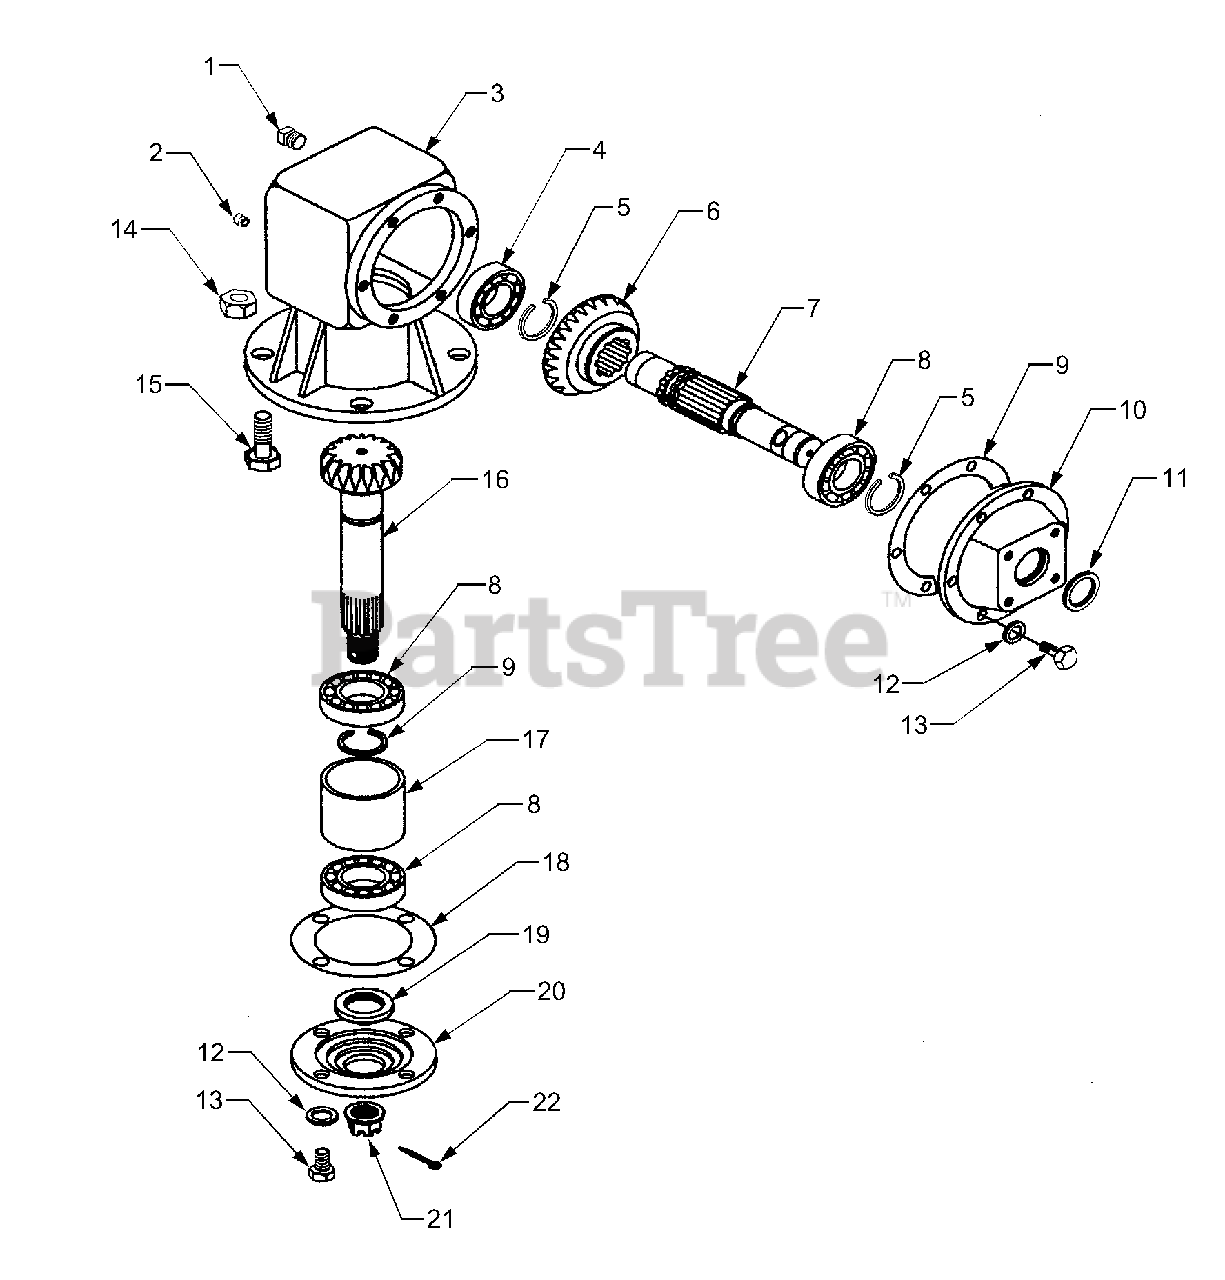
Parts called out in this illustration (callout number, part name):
3	Gearbox Housing
7	Input Shaft
10	Gearbox Cover
12	Lock Washer, 10mm
13	Bolt, 10mm x 25
14	Stover Nut, 16mm
15	Bolt, 16mm x 55
16	Pinion Gear
20	Ouput Cover
